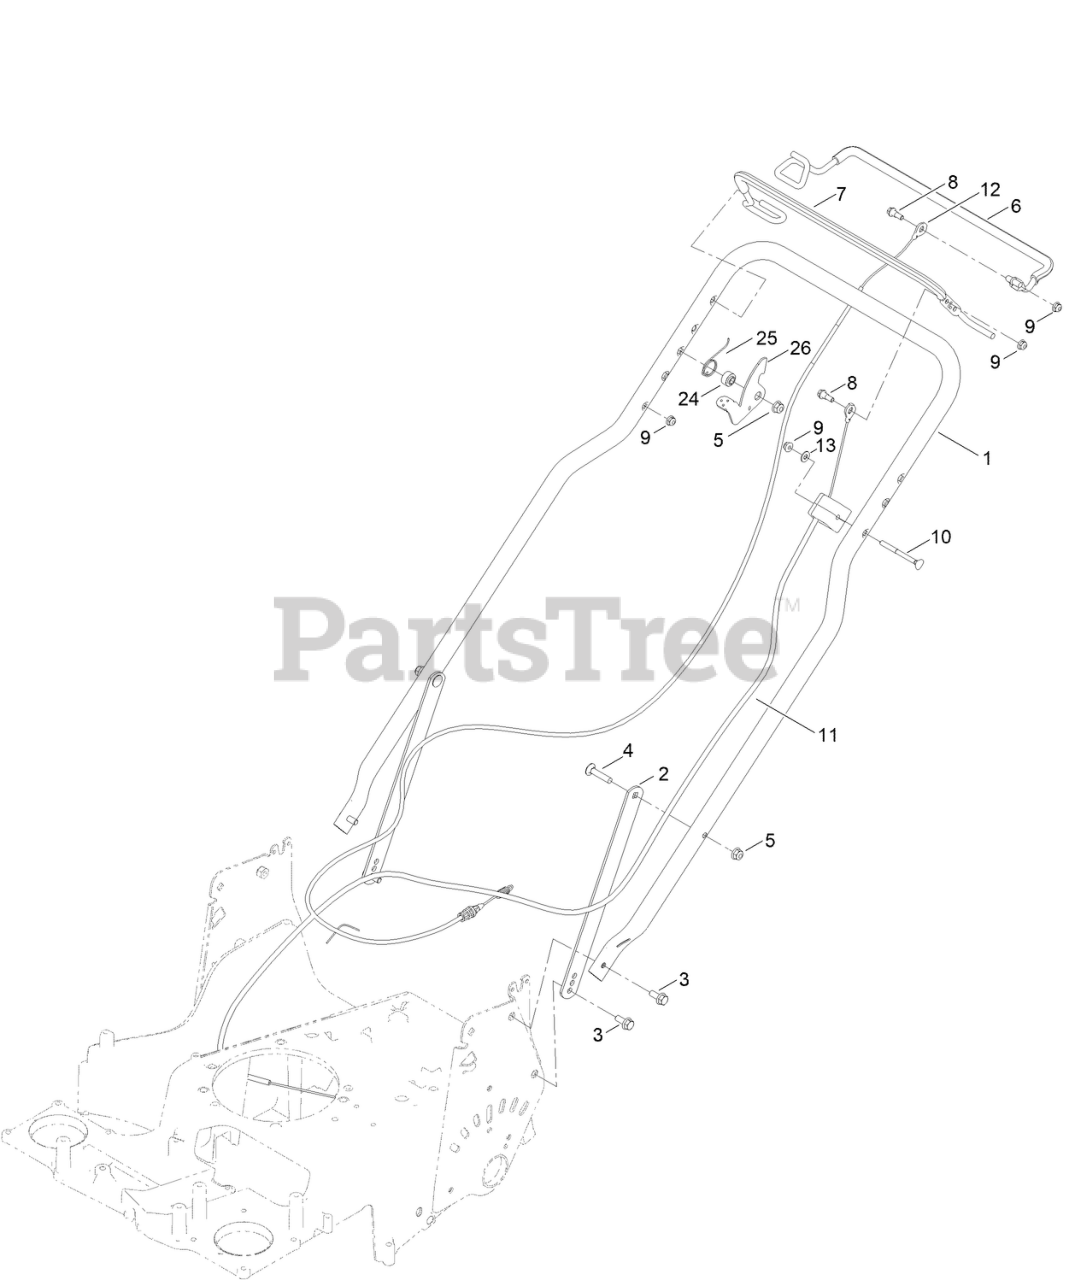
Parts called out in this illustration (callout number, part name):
2	SUPPORT-HANDLE
3	SCREW-HHF
4	BOLT-CARR
5	NUT-HF, NI
6	BAIL-TRACTION, COATED
7	BAIL-BBC, COATED
8	BOLT-SHOULDER
9	NUT-HF
10	SCREW-HANDLE
11	CABLE-BBC
12	CABLE-TRACTION
13	WASHER-FLAT
24	BUSHING-STEPPED
25	SPRING-LEVER, BBC
26	LEVER-BBC
